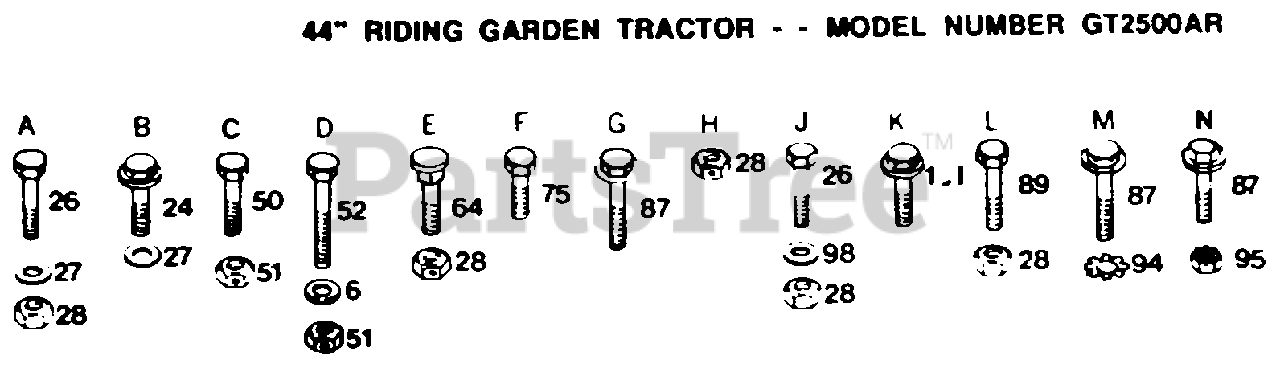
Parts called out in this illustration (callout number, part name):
6	WASHER
24	SCREW
26	BOLT
27	WASHER
50	BOLT
52	BOLT HEX
64	BOLT
75	SCREW
87	SCREW LT
94	LOCKWASHER
95	NUT
98	WASHER
101	SCREW
